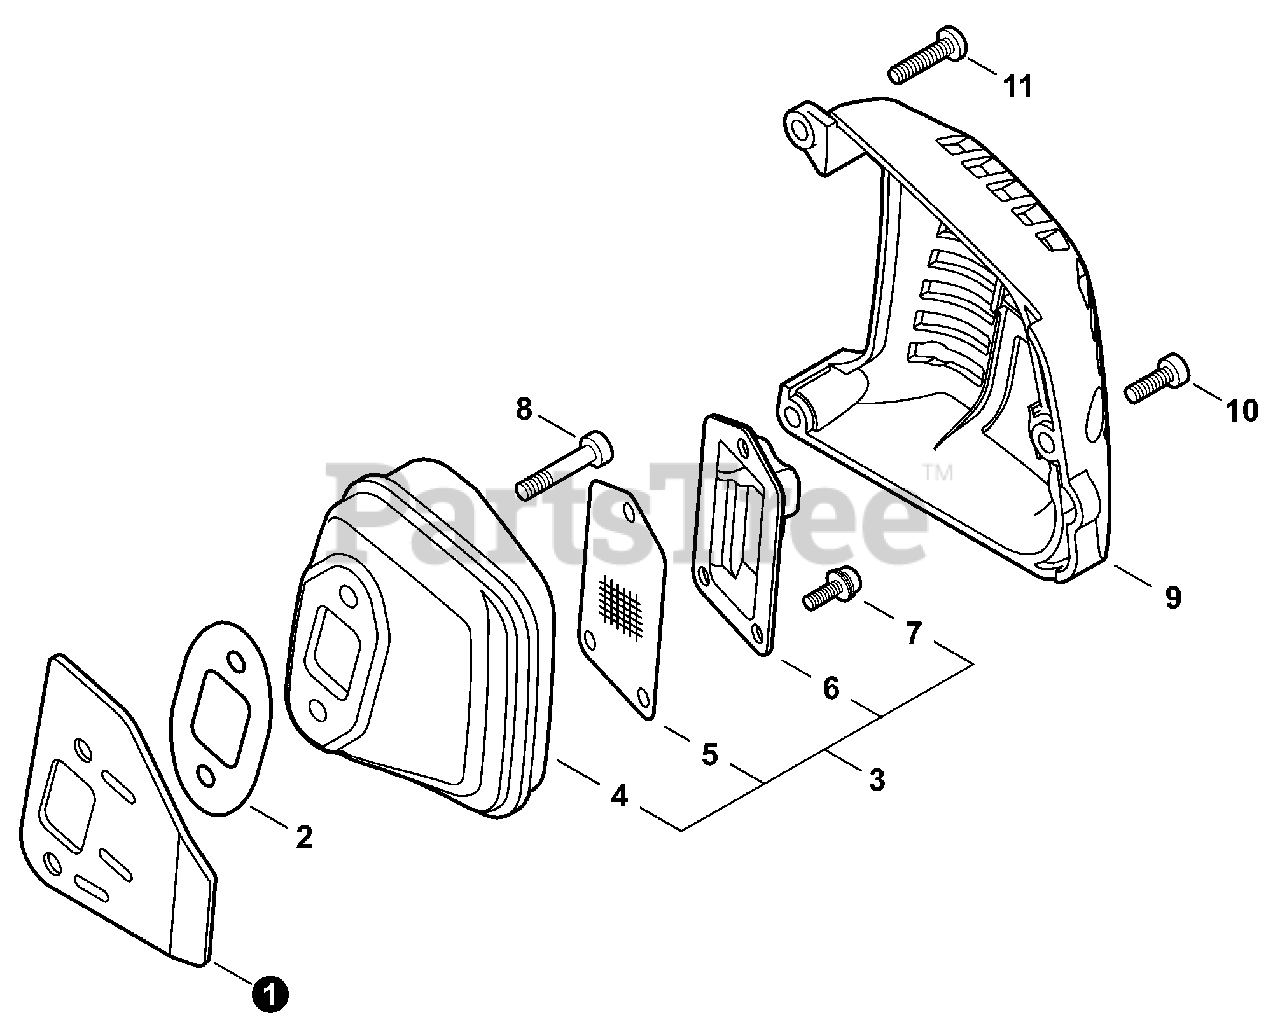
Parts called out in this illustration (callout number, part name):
1	HEAT SHIELD, EXHAUST
2	GASKET, EXHAUST
3	MUFFLER ASSY
4	MUFFLER
5	SCREEN, SPARK ARRESTER
6	GUIDE, EXHAUST
7	SCREW 4×10
8	BOLT 5×40
9	COVER, MUFFLER
10	BOLT, TORX 5×16
11	BOLT, TORX 5×20
